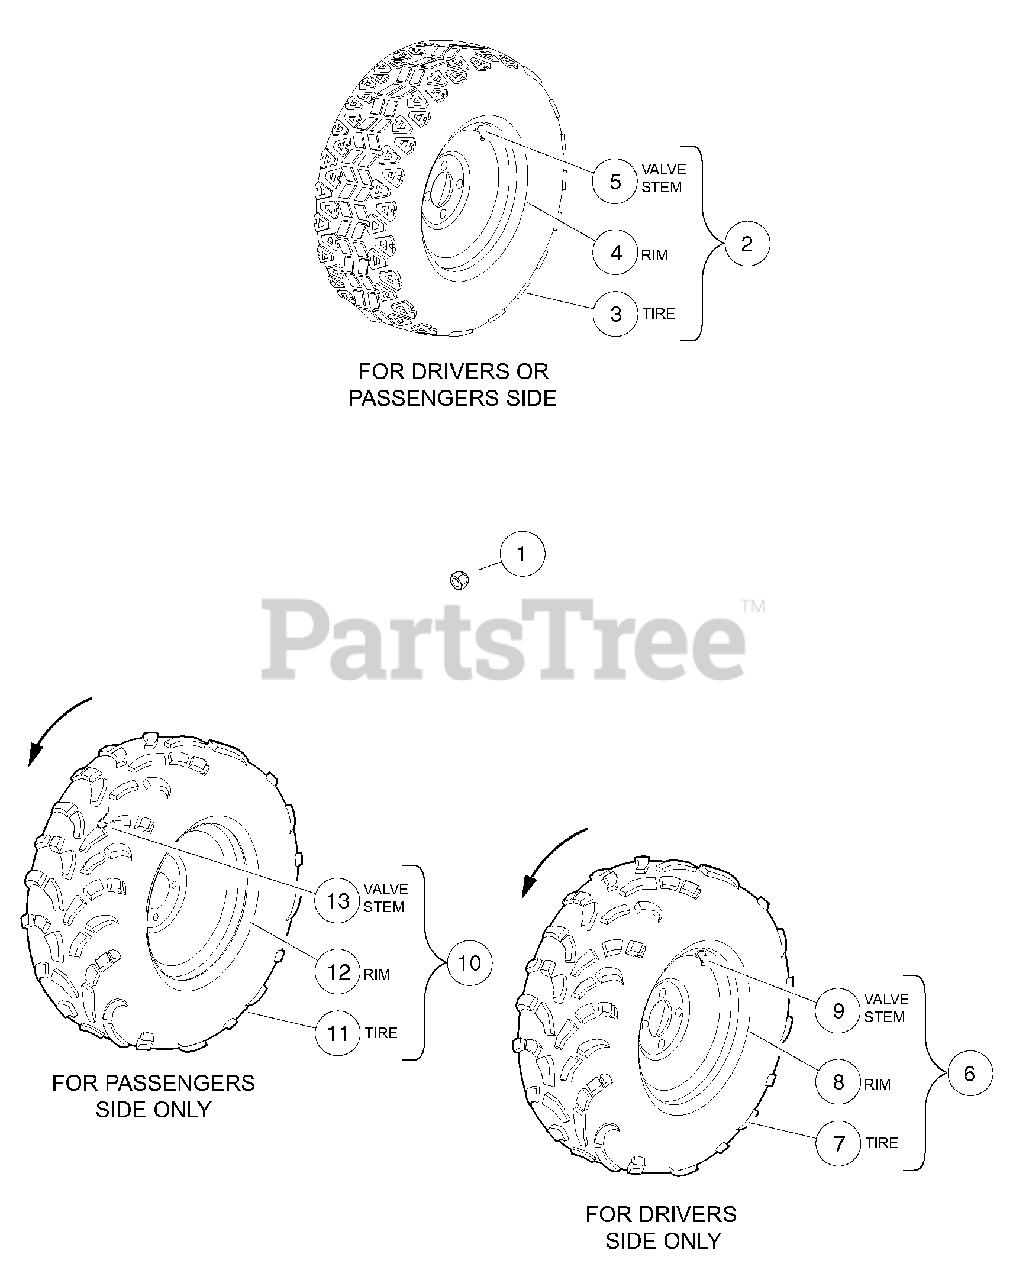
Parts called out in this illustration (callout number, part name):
1	Nut, Lug, 1/2-20 SAE J2283
2	Black Tire Asm HDAT 10.5 In
3	Heavy Duty All Terrain Tire, 25"
4	Wheel, All trail, 10 Win, Black
5	Valve Stem
6	Black Tire Asm Mud 11.0 In Left-Han
7	Mud Tire, 25"
8	Wheel, All trail, 10 Win, Black
9	Valve Stem
10	Black Tire Asm Mud 11.0 In Right-Hand
11	Mud Tire, 25"
12	Wheel, All trail, 10 Win, Black
13	Valve Stem
